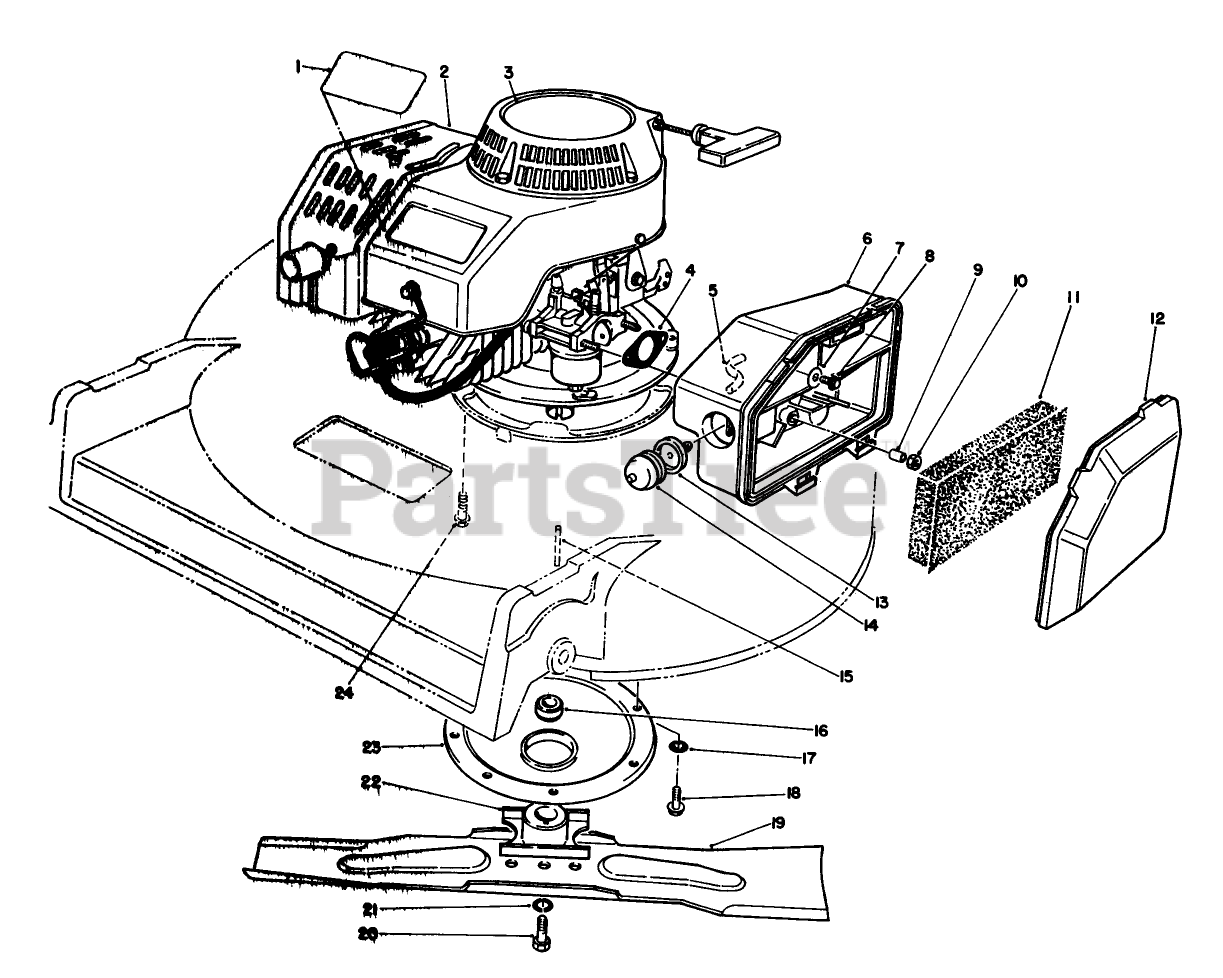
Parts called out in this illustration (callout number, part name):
1	DECAL - PROLINE
2	ENGINE ASM
3	DECAL-2 CYC RECOIL COMM
4	GASKET-AIR CLEANER
5	HOSE-PRIMER
6	BODY-AIR CLEANER
7	WASHER-FLAT
8	SCREW-HH
9	SPACER
11	ELEMENT-AIR CLEANER
12	COVER-AIR CLEANER
13	BODY-PRIMER
14	BULB-PRIMER
15	KEY-SQUARE
16	SPACER-BLADE RETAINER
17	WASHER-LOCK, INTERNAL
18	SCREW-HWHTF
19	Key
20	SCREW-BLADE
21	WASHER-LOCK
22	RETAINER-BLADE
23	PROTECTOR-CRANKSHAFT
24	SCREW-HHF
